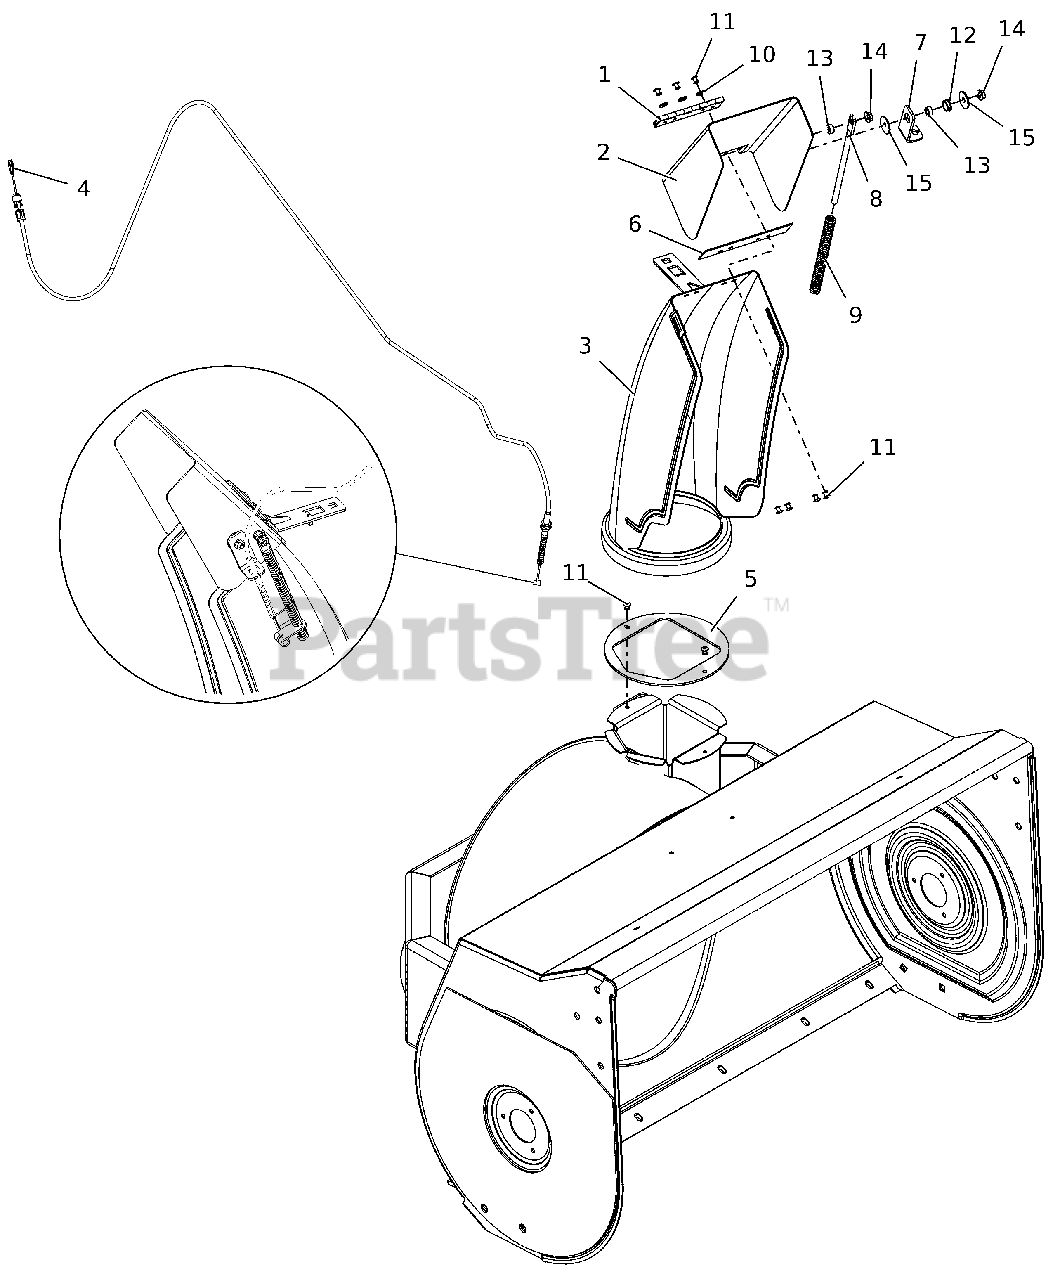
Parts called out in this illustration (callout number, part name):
2	KIT,SERVICE - CAP W/ DECAL
3	WLDMT, 32" DISCHARGE CHUTE
4	CABLE, DEFLECTOR DELUXE
5	BAFFLE, DISCHARGE NECK
6	CAP SEAL 5.50
7	BRKT,CHUTE,CABLE ANCHOR
8	ROD,DEFLECTOR CAP
9	SPRING,COMPRESSION
10	WSHR-FL-STL .196X.50X.06 ZC120
11	RVT-POP .187 YZ
12	BUSHING, POLYLINER-.50 SNAPIN
13	BSHG-SLV .265X.500X.219
14	NUT-LK-CTR-FLG .25-20 ZC120
15	WSHR,FLT .281X1.000X.063 ZCC
